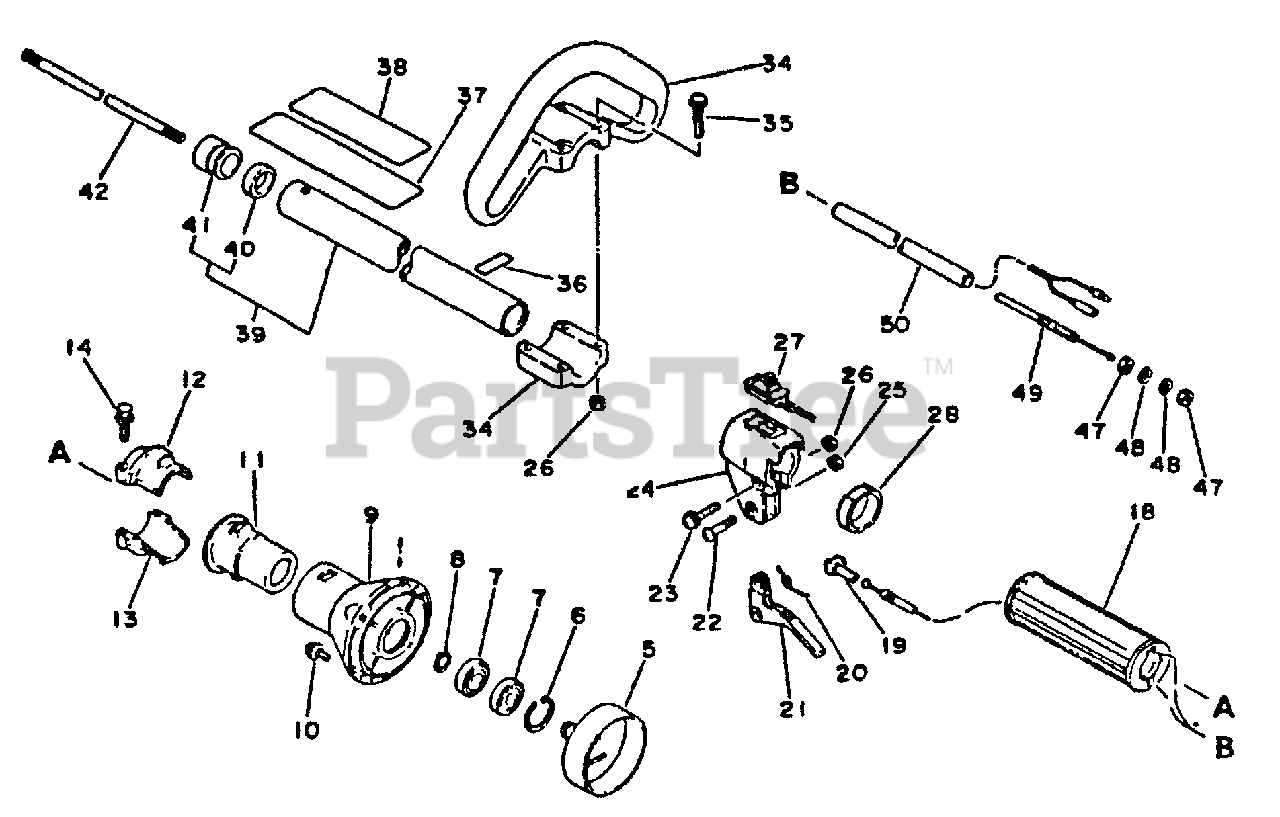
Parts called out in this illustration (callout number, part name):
5	DRUM, CLUTCH
6	RING, SNAP 28
7	BEARING, BALL 6001
8	RING, RETAINING - 12
9	CASE, CLUTCH
10	SCREW 5×16
12	HOLDER
13	HOLDER
14	BOLT - 5×25
18	GRIP
19	GUIDE, CABLE
20	SPRING, THROTTLE
21	TRIGGER, THROTTLE
23	SCREW 5×30
24	BRACKET, THROTTLE
25	LOCKNUT - 5
26	NUT M5
27	IGNITION SWITCH ASSY
34	LOOP HANDLE ASSY
35	SCREW 5×35
37	LABEL - CAUTION
38	LABEL - CAUTION
39	MAIN PIPE ASSY
42	DRIVESHAFT
48	WASHER 6.5×11.5×0.8
49	CABLE, THROTTLE
